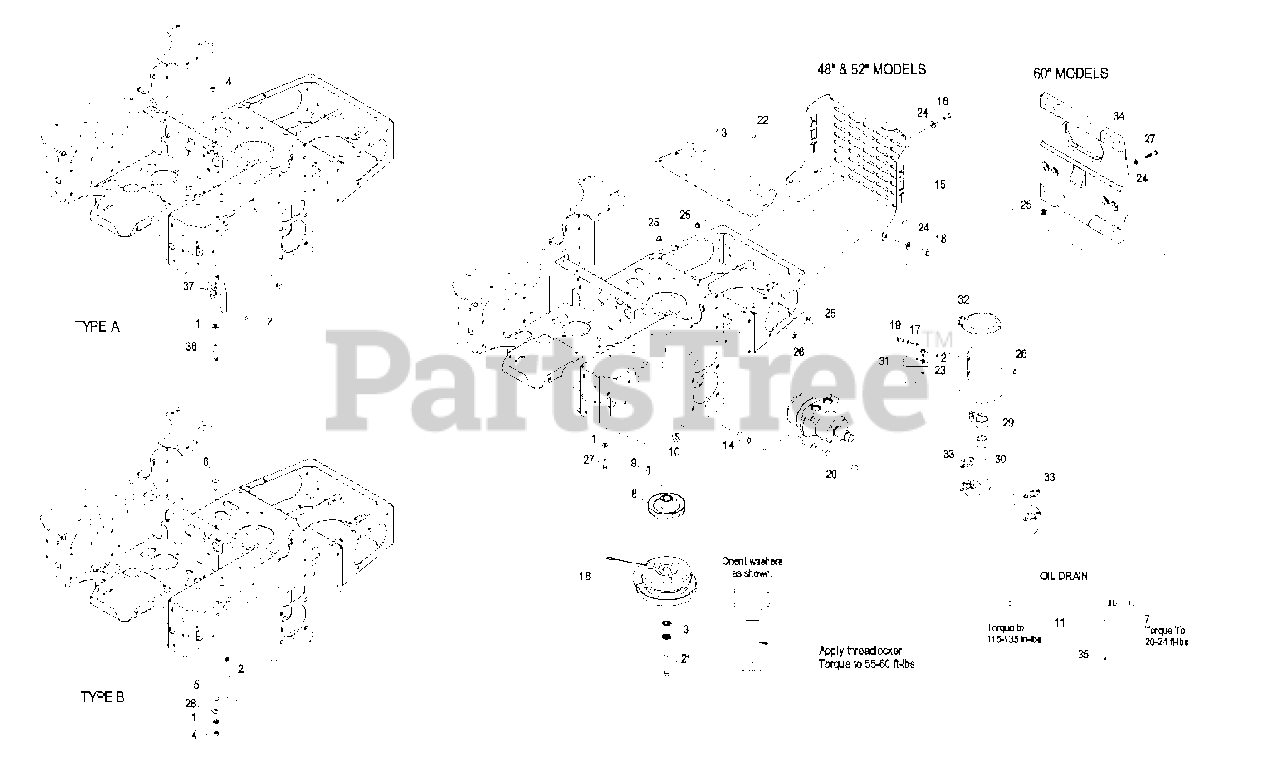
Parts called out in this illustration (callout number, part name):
1	WASHER-SPRING
2	TIE-PLASTIC
3	WASHER-SPRING
4	NUT-LOCK, NI
5	KIT,CLUTCH ANCHOR
6	Bolt-Carriage 5/16-18 X 1 1/4
10	NUT-HHF
12	SCREW-HH
13	DEFLECTOR-SHORT
14	SPACER-MOTOR, WHEEL
14	SPACER-WHEEL, LONG
15	BUMPER-REAR
15	KIT, CLUTCH LCT 60
16	KIT, CLUTCH LCT 48/52
17	WASHER-SPRING
18	SCREW-HH
19	SCREW-HH
20	SCREW-HH
21	SCREW-HH
22	SCREW-CARR
23	WASHER-LOCK
24	WASHER-PLAIN
27	SCREW-HH
28	WASHER-FLAT
29	CLAMP-MUFFLER, 1.25 FLAT
30	MANIFOLD, EXAUST 21/23 BV
31	BRACKET,EXHAUST 21BV
32	MUFFLER
33	Gasket (21hp & 23hp)
34	WEIGHT-NOTCHED, 60 LB
35	CABLE TIE-PLASTIC
36	SCREW-HH
37	ANCHOR-CLUTCH
